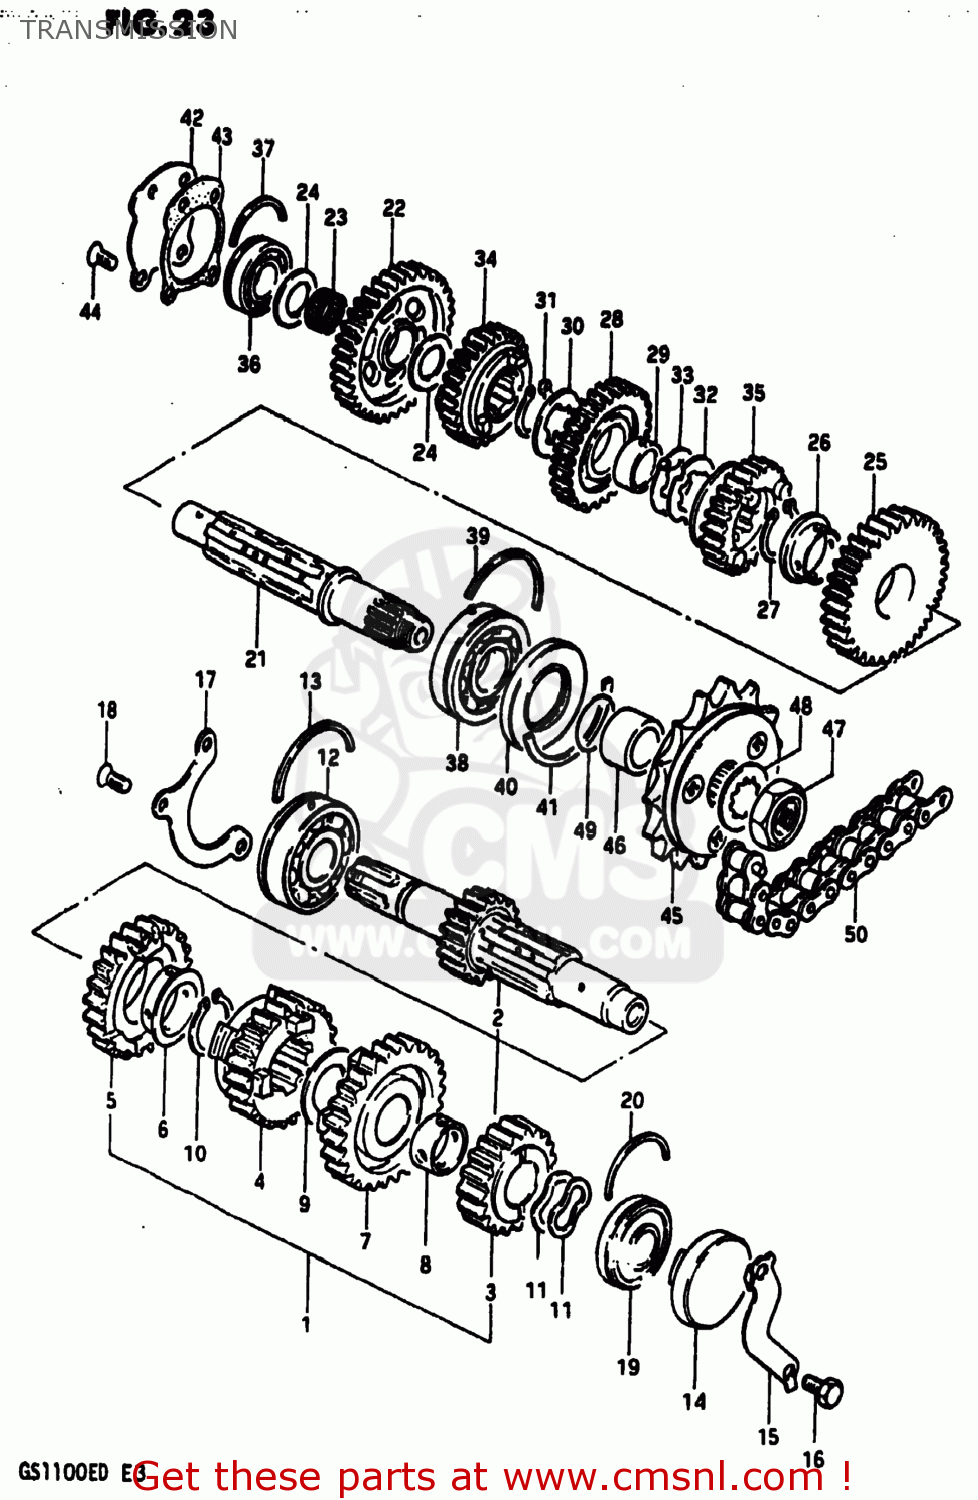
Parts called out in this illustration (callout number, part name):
1	SHAFT,COUNTER
2	SHAFT,COUNTER
3	GEAR,SECOND DRIVE
4	GEAR,3RD DRIVE(NT:21)
5	GEAR,FOURTH DRIVE
6	BUSH(28X32X2)
7	GEAR,FIFTH DRIVE
8	BUSHING
9	WASHER
10	CIRCLIP
11	WASHER
12	BEARING(25X62X17)
13	C-RING
14	PLUG
15	RETAINER,CL PUSH ROD OIL SEAL
16	BOLT
17	RETAINER,CNTR SHAFT BEARING
18	SCREW
19	BEARING(20X47X14)
20	C RING
21	SHAFT,DRIVE
22	GEAR,FIRST DRIVEN (NT:35)
23	BEARING(20X24X10).8
24	WASHER
25	GEAR,SECOND DRIVEN
26	BUSH(28X32X2)
27	CIRCLIP
28	GEAR,THIRD DRIVEN
29	BUSH,3RD DRIVEN GEAR
30	WASHER,LOCK
31	CIRCLIP
32	WASHER,LOCK
33	WASHER
34	GEAR,FOURTH DRIVEN
35	GEAR,FIFTH DRIVEN
36	BEARING
37	C RING
38	BALL BEARING 25X62X17
39	C-RING
40	SEAL,OIL(32X62X7)
41	C RING
42	PLATE,DRIVE SHAFT
43	GASKET,DRIVESHAFT PLATE (MCA)
44	SCREW
45	SPROCKET,ENGINE
46	SPACER(25X32X18.6)
47	NUT
48	WASHER
49	O RING(D:1,ID:24.5)
50	CHAIN ASSEMBLY,DRIVE
